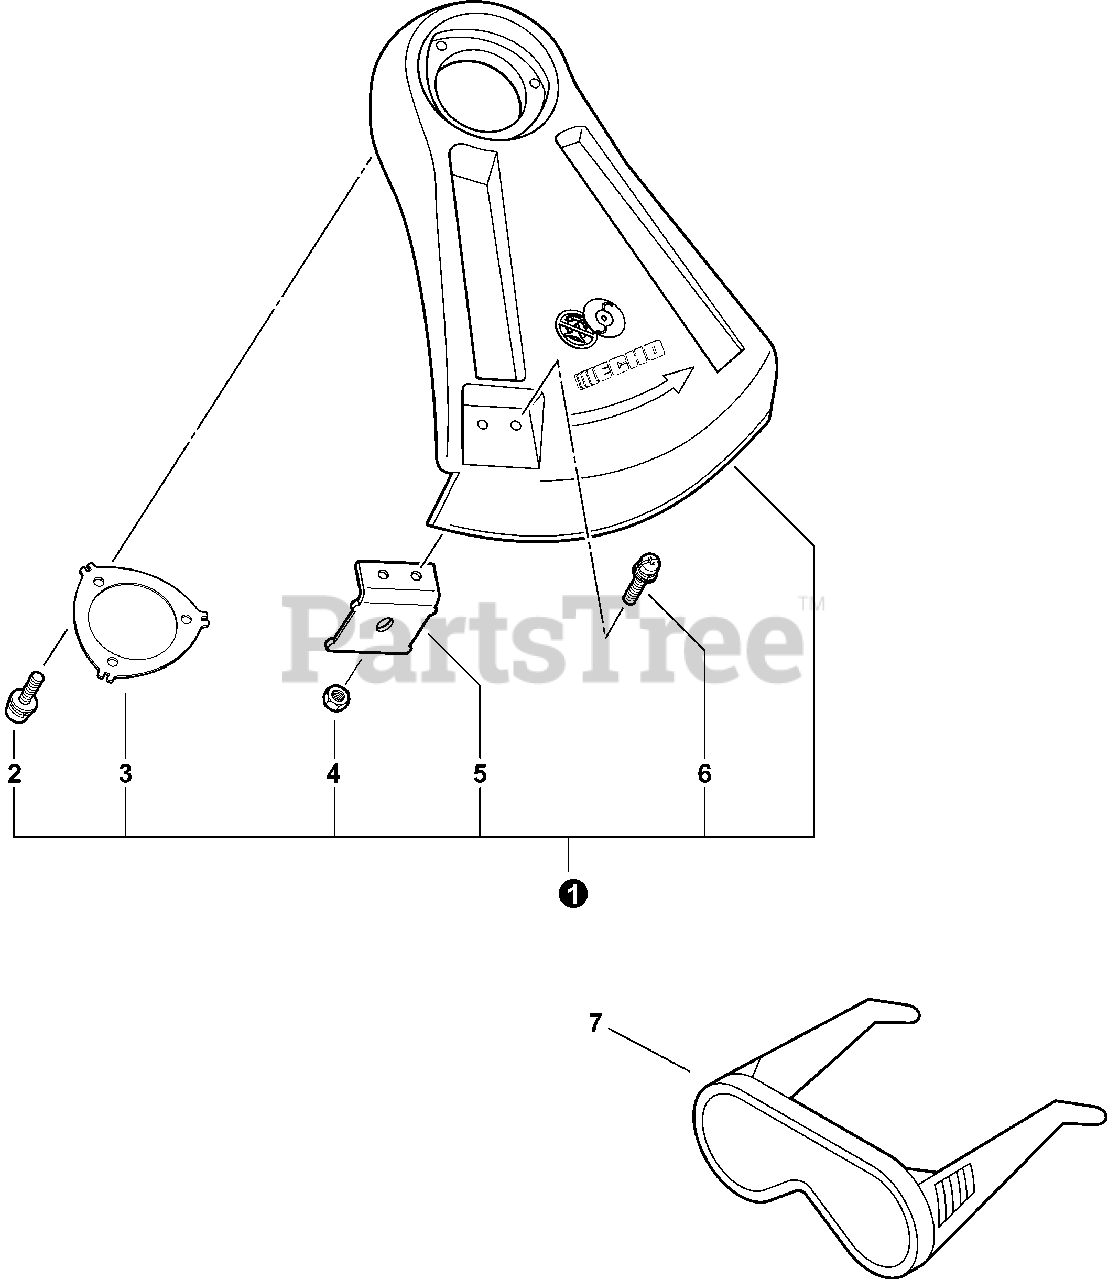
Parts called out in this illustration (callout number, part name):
1	DEBRIS SHIELD KIT
2	BOLT, TORX 5×16
3	PLATE, SHIELD
4	NUT M5
5	CUTTER, LINE
6	BOLT, TORX 5×12
7	GLASSES, SAFETY
